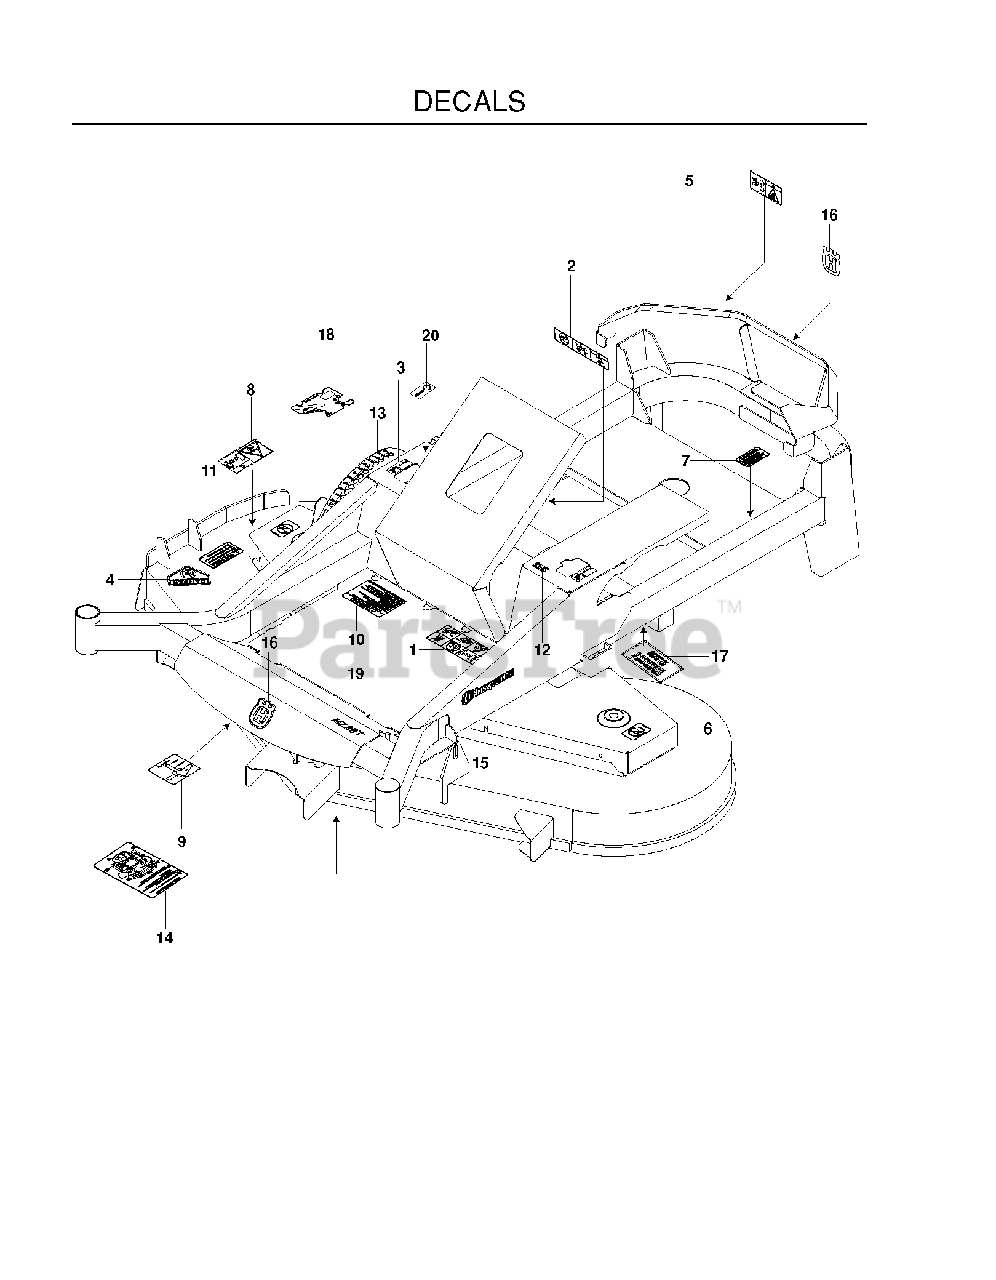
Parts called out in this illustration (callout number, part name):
1	DECAL, WARNING
2	EURO DECAL-BATTERY WARNIN6
3	DECAL, MOTION CONTROL
4	DECAL, CPSC
5	DECAL, BELT DRIVE
6	DECAL, NO STEP
7	DECAL, PROP. 65
8	DECAL, EURO SEVERING
9	DECAL, BELT ROUTING
10	DECAL, WARNING
11	DECAL, CAUTION
12	DECAL, F.S.T.
13	DECAL, HEIGHT ADJUST
14	DECAL, SERVICE
15	RP.DECAL.BADGE.170MM.TEXTLOGO
16	DECAL.AUGER.HUSQ.CROWN.SNOW
17	HG_DECAL, ZT-3400
18	DECAL, CONSOLE
19	DECAL, MZ 28T
20	DECAL, ECM, AUSTRALIA
